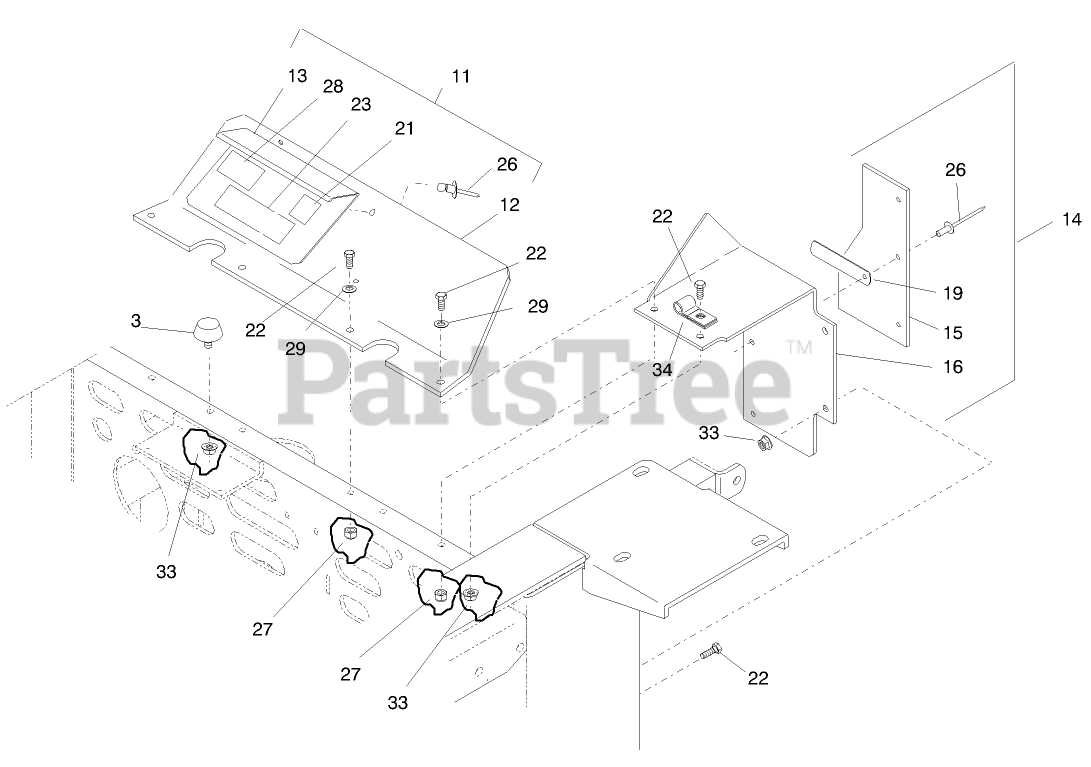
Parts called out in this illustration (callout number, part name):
3	Bumper
11	Shield-Lift ASM
12	Shield-Engine
13	Shield-Lift
14	Shield LH
15	Shield-Engine
16	Baffle
18	Shield RH
19	Clip
20	Baffle-Engine
21	Decal-Guard
22	SCREW-HH
23	Decal-Belt Drive
25	SCREW-HH
26	Pop Rivet
27	NUT-LOCK
28	Decal-Important
29	WASHER-FLAT
33	NUT-HF
34	Clip
